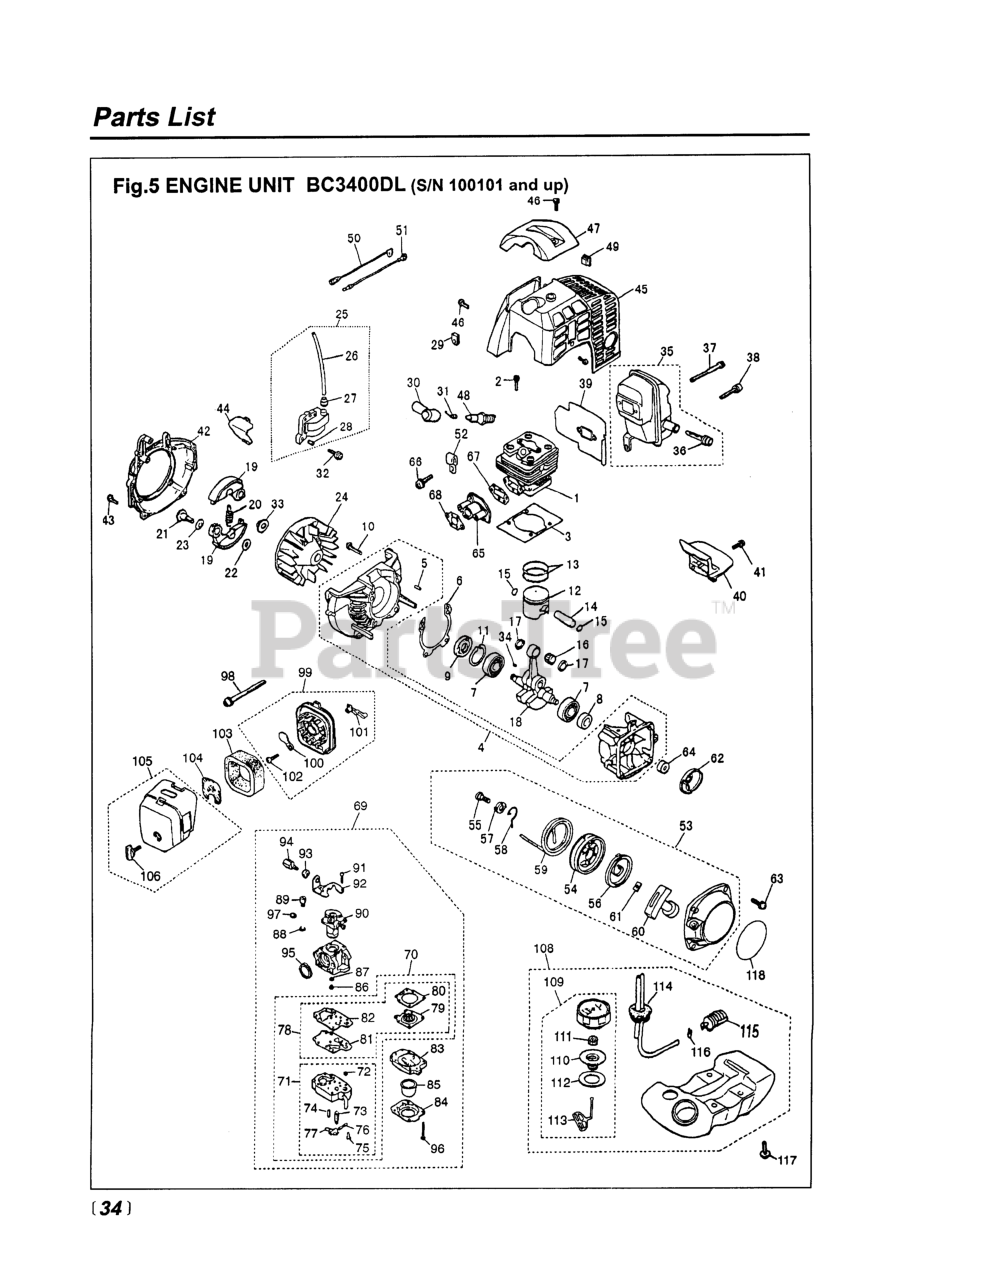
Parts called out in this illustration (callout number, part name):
1	CYLINDER
2	BOLT, M5 X 22
3	GASKET, BASE
4	CRANKCASE COMP (RPLS. -21100)
5	PIN
6	GASKET
8	SEAL
9	SEAL, OIL (RPLS 1200-21220)
10	BOLT, M5 X 30
11	RING, SNAP, M32 x 1.2
12	PISTON
13	RING, PISTON
14	PIN, PISTON
15	RING, SNAP
16	BEARING
17	WASHER
18	CRANKSHAFT COMPL
19	CLUTCH SHOE
20	SPRING
21	SCREW
22	WASHER
23	WASHER (RPLS. -51240)
24	ROTOR
25	COIL ASSEMBLY
29	GROMMET
30	CAP
31	SPRING
32	BOLT, M4 x 22
34	KEY
35	MUFFLER ASSEMBLY
36	ARRESTER (RPLS 5850-15140)
37	BOLT, M5 x 60
38	BOLT (REPLACES 01252-30514)
39	GASKET, MUFFLER (RPLS -15210)
40	PLATE (RPLS-15220)
41	SCREW,M5 X 14 (RPLS 1400-15510
43	BOLT M5 x 20 (RPLS -12280)
45	COVER
46	SCREW M5 x 12
47	GUARD
50	CORD
51	CORD, EARTH
52	CLAMP
53	RECOIL ASSEMBLY
54	REEL
55	SCREW
56	SPRING, SPIRAL
57	COLLAR
58	ARM
59	ROPE (USE 4810-75160)
60	KNOB
61	PLATE, STOPPER
62	PULLEY
63	SCREW, M6 x 14
65	INSULATOR (REPLACES -13160)
66	SCREW
67	GASKET, INSULATOR
68	GASKET, CARBURETOR
69	CARBURETOR ASSEMBLY
71	BODY, PUMP
72	SCREEN
73	VALVE, INLET
75	SCREW
76	PIN
77	LEVER
79	DIAPHRAGM
80	GASKET, DIAPHRAGM
81	DIAPHRAGM, PUMP
82	GASKET, PUMP
83	BODY, PURGE
84	COVER, PUMP
85	PUMP, PRIMING
86	JET
87	RING, O
88	RING
89	SWIVEL
90	VALVE ASSY
91	SCREW
93	NUT, CABLE ADJUSTER
94	SCREW, CABLE ADJUSTER
95	RING, PACKING
96	SCREW
97	WASHER
99	BODY ASSEMBLY
100	PLATE, CHOKE
101	LEVER, CHOKE
102	SCREW (REPLACES 50030272)
103	ELEMENT
104	SCREEN
106	KNOB (RPLS -82220)
108	TANK ASSY (RPLS 4700-85001)
109	CAP ASSY (RPLS -85201)
110	HOLDER (REPLACES -85230)
111	FILTER
112	PACKING
113	STOPPER
114	PIPE COMPLETE
115	FILTER ASSY
116	CLIP (REPLACES 2841-31280)
117	SCREW, M5 X 22
118	LABEL, RECOIL
